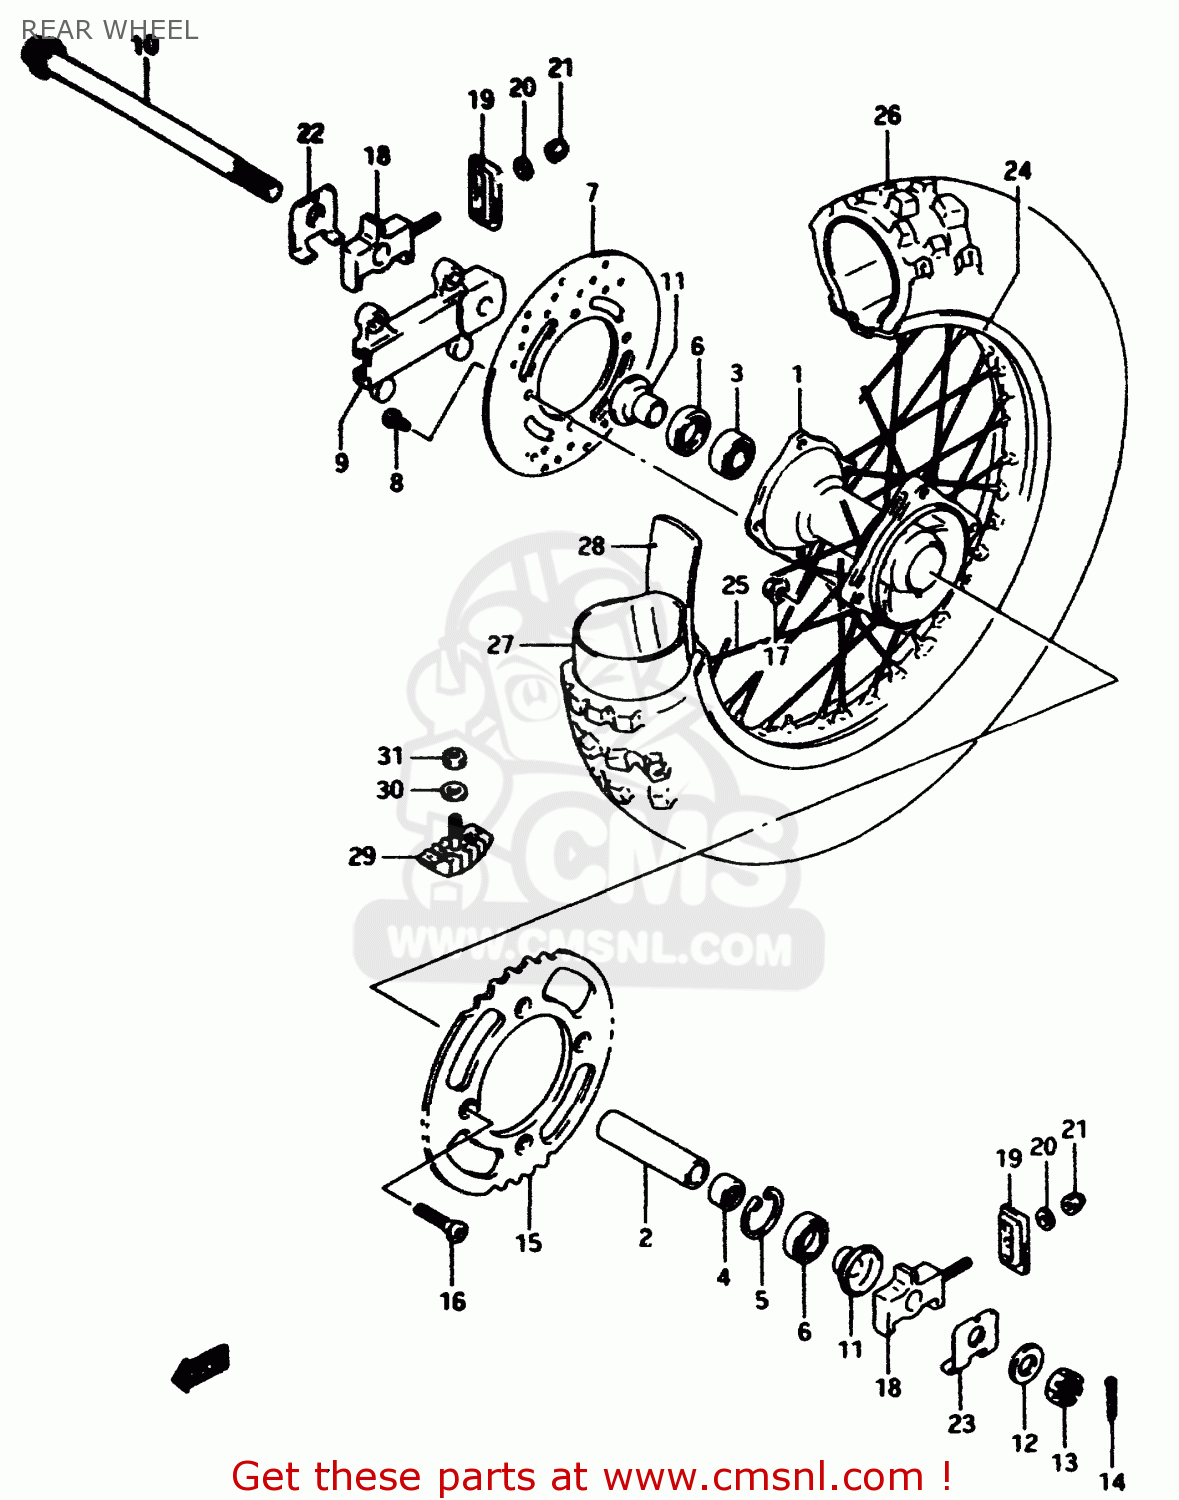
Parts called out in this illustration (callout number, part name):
1	HUB,RR WHEEL
2	SPACER,RR HUB BEARING
3	BEARING
4	BEARING(15X35X11)
5	CIRCLIP
6	SEAL,OIL(20X35X7)
7	DISC,REAR BRAKE
8	SCREW
9	BRACKET,RR AXLE
10	AXLE,RR
11	SPACER,RR AXLE
12	WASHER
13	NUT
14	COTTER PIN
15	SPROCKET,RR(49T)
16	BOLT(8X30.5)
17	NUT
18	ADJUSTER,CHAIN
19	PLATE,CHAIN ADJUSTER
20	WASHER
21	NUT 6MM
22	WASHER,CHAIN ADJUSTER RH
23	WASHER,CHAIN ADJUSTER,L
24	RIM,RR WHEEL(1.60X14 AL)
25	SPOKE ASSY,RR WHEEL
26	TIRE,RR(90/100 14)
27	TUBE ASSY,WHEEL INNER
28	PROTECTOR,WHEEL,INNER
29	STOPPER,BEAD(1.85)
30	WASHER
31	NUT
